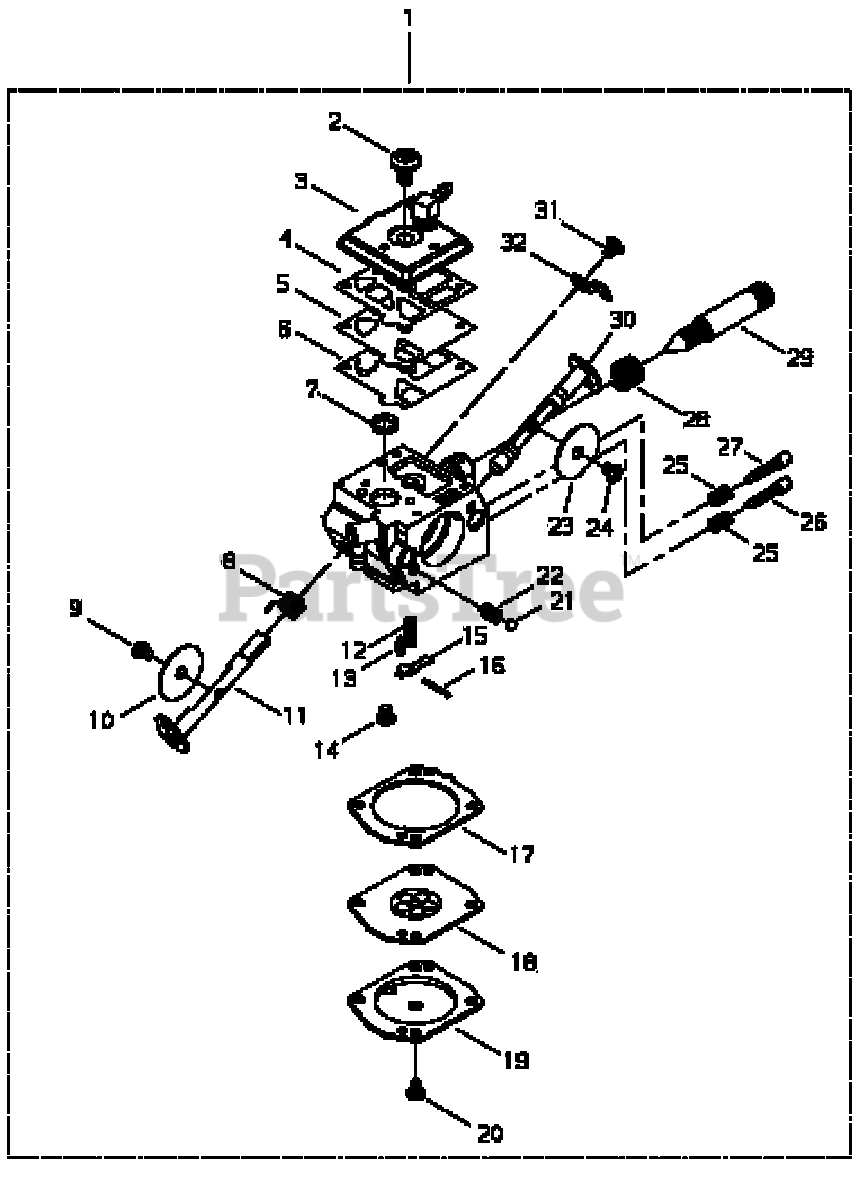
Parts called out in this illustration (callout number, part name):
1	CARBURETOR ASSY
2	SCREW
3	COVER ASSY, PUMP
4	GASKET, FUEL PUMP
5	DIAPHRAGM, PUMP
6	DIAPHRAGM, PUMP
7	SCREEN, FUEL INLET
8	SPRING, THROTTLE RETURN
9	SCREW ASSY
10	VALVE, THROTTLE
11	SHAFT ASSY
12	SPRING, METERING LEVER
13	VALVE, INLET NEEDLE
14	SCREW, METERING LEVER PIN
15	LEVER
16	PIN, METERING LEVER
17	GASKET, METERING DIAPHRAGM
18	DIAPHRAGM, METERING
19	COVER, METERING DIAPHRAGM
20	SCREW
21	BALL, CHOKE FRICTION
22	SPRING
23	VALVE, CHOKE
24	SCREW
25	SPRING, NEEDLE
26	NEEDLE, HIGH SPEED
27	NEEDLE, LOW SPEED
28	SPRING, IDLE ADJUST
29	SCREW, IDLE ADJUST
30	SHAFT ASSY
31	SCREW
32	STOP, THROTTLE
